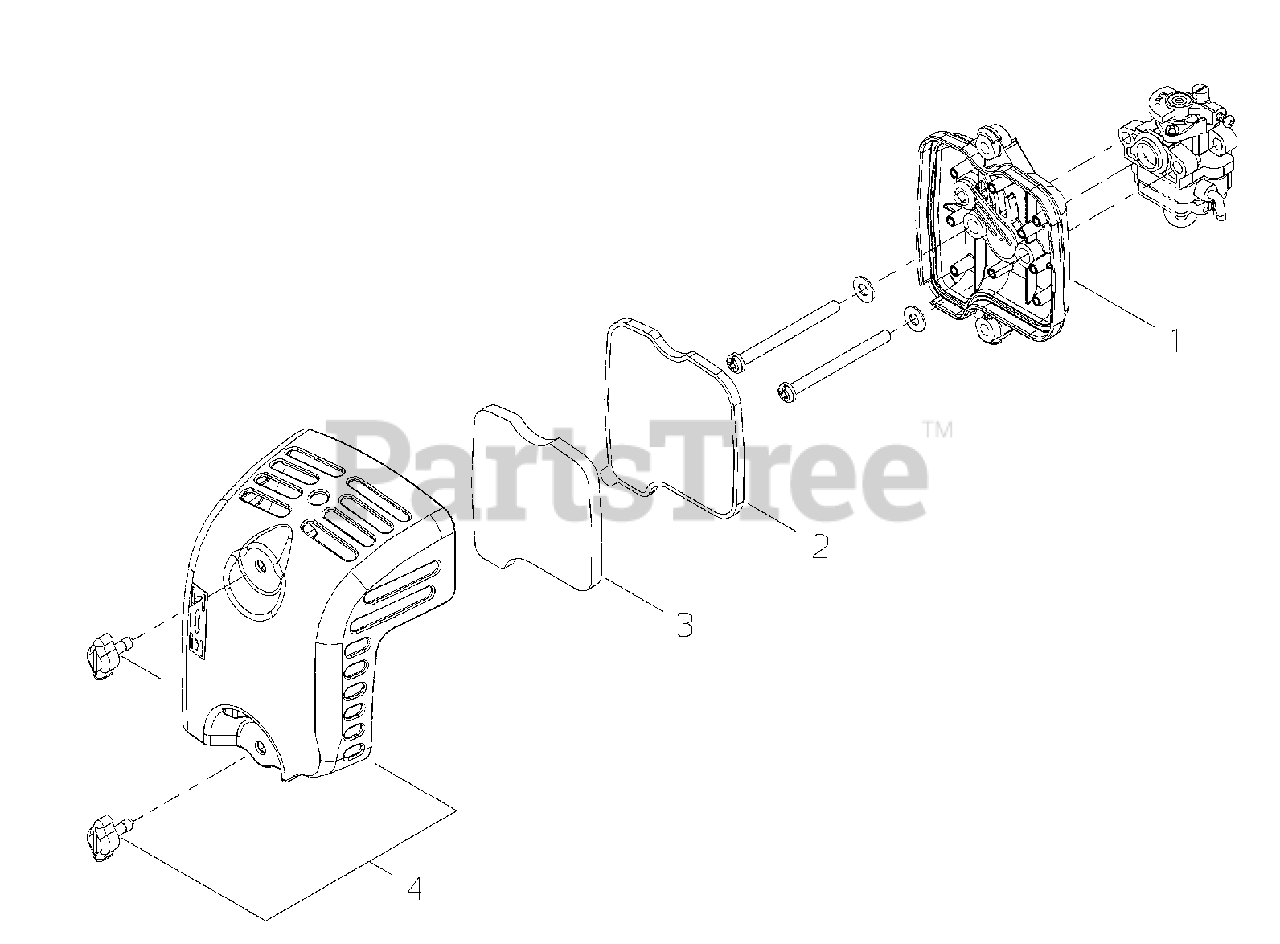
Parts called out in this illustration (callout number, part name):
1	AIR FILTER CASE ASSY
2	FILTER, AIR
3	PRE-FILTER - FOAM
4	CLEANER COVER ASSY
